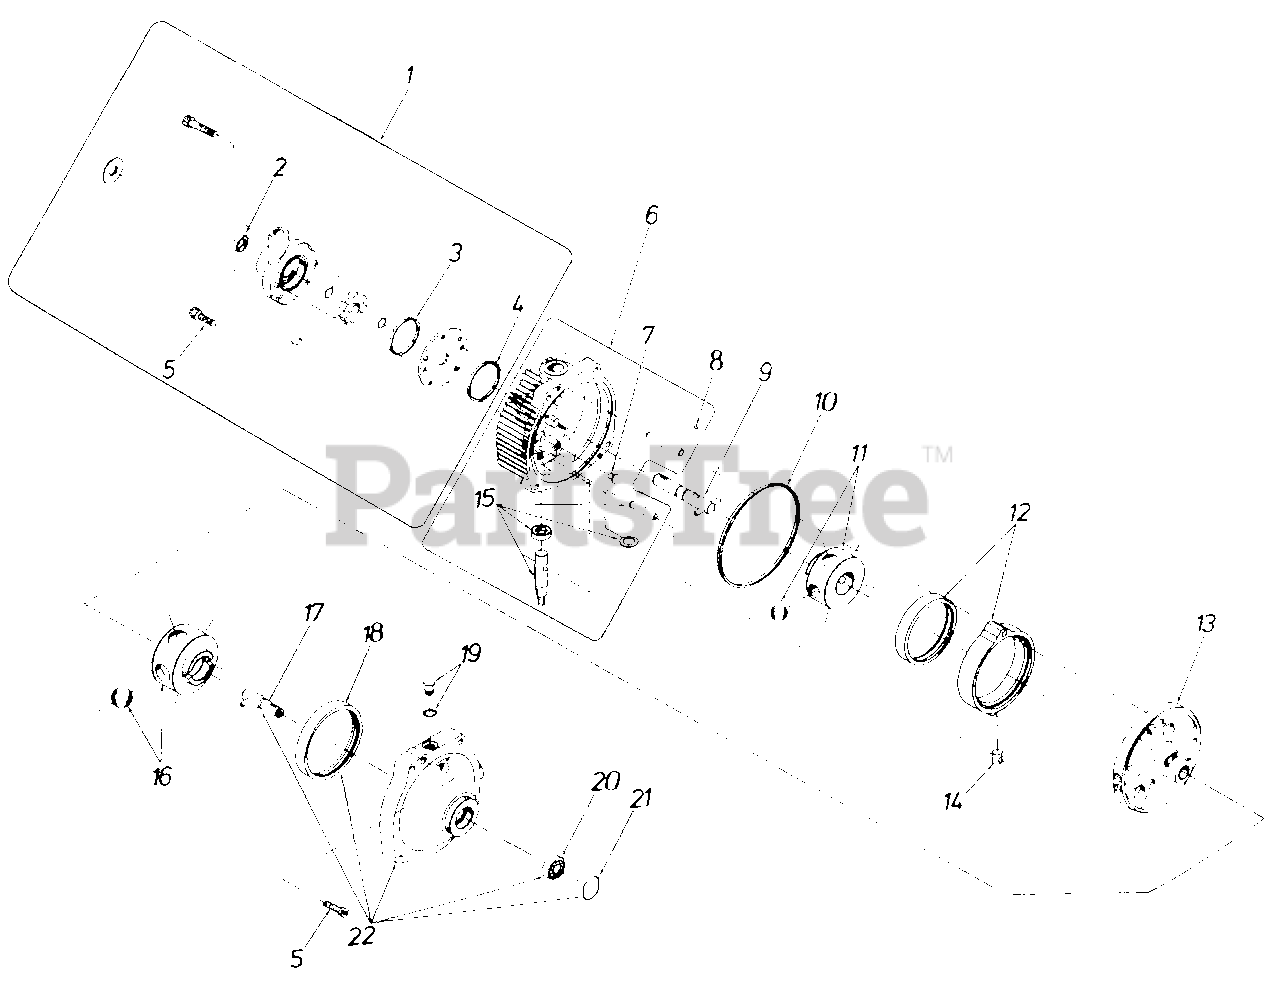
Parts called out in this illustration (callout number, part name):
1	Charge Pump Kit
2	Oil Seal
3	Square Cut Sea Ring .036
4	Square Cut Seal Ring .038
5	Socket Head Cap Screw 5/16-18 x 1.25" Long
6	Cover Subassembly
8	Drive Pin
9	Input Shaft Subassembly
10	Square Cut Seal Ring .166
11	Pump Rotor-Ball Subassembly
12	Cam Ring Subassembly
13	Pintle Subassembly
14	Cam Ring Insert
15	Control Shaft Kit
16	Motor Rotor-Ball Subassembly
17	Output Shaft Subassembly
18	Motor Race
19	"O"-Ring Plug Subassembly
20	Ball Bearing
21	Retaining Ring
22	Body Subassembly
